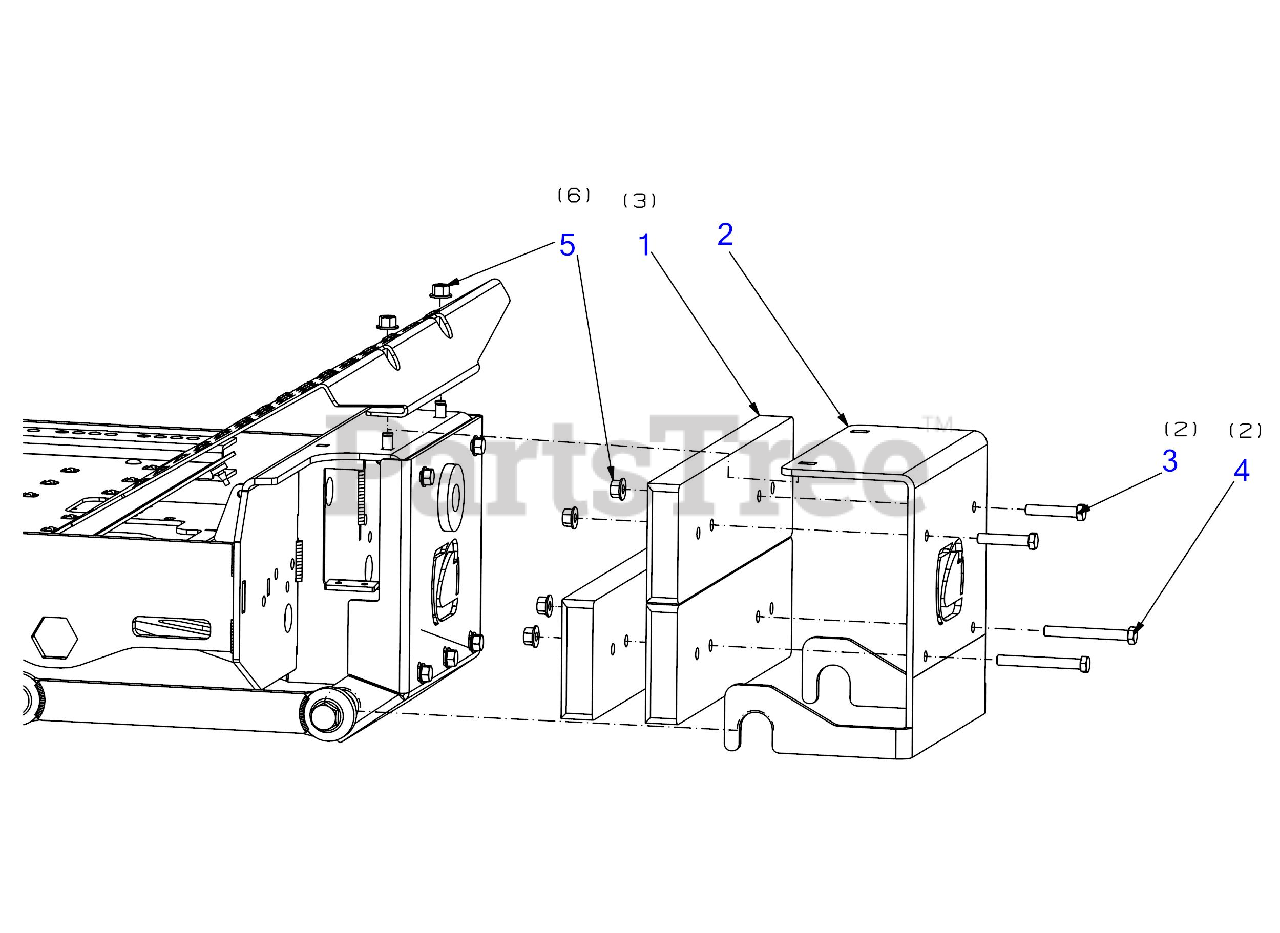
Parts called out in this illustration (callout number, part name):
3	SCREW 3/8-16 x 2.0 GR 8
4	SCREW 3/8-16 x 3.25 GR8
5	NUT-CTRLCK FLG HEX
